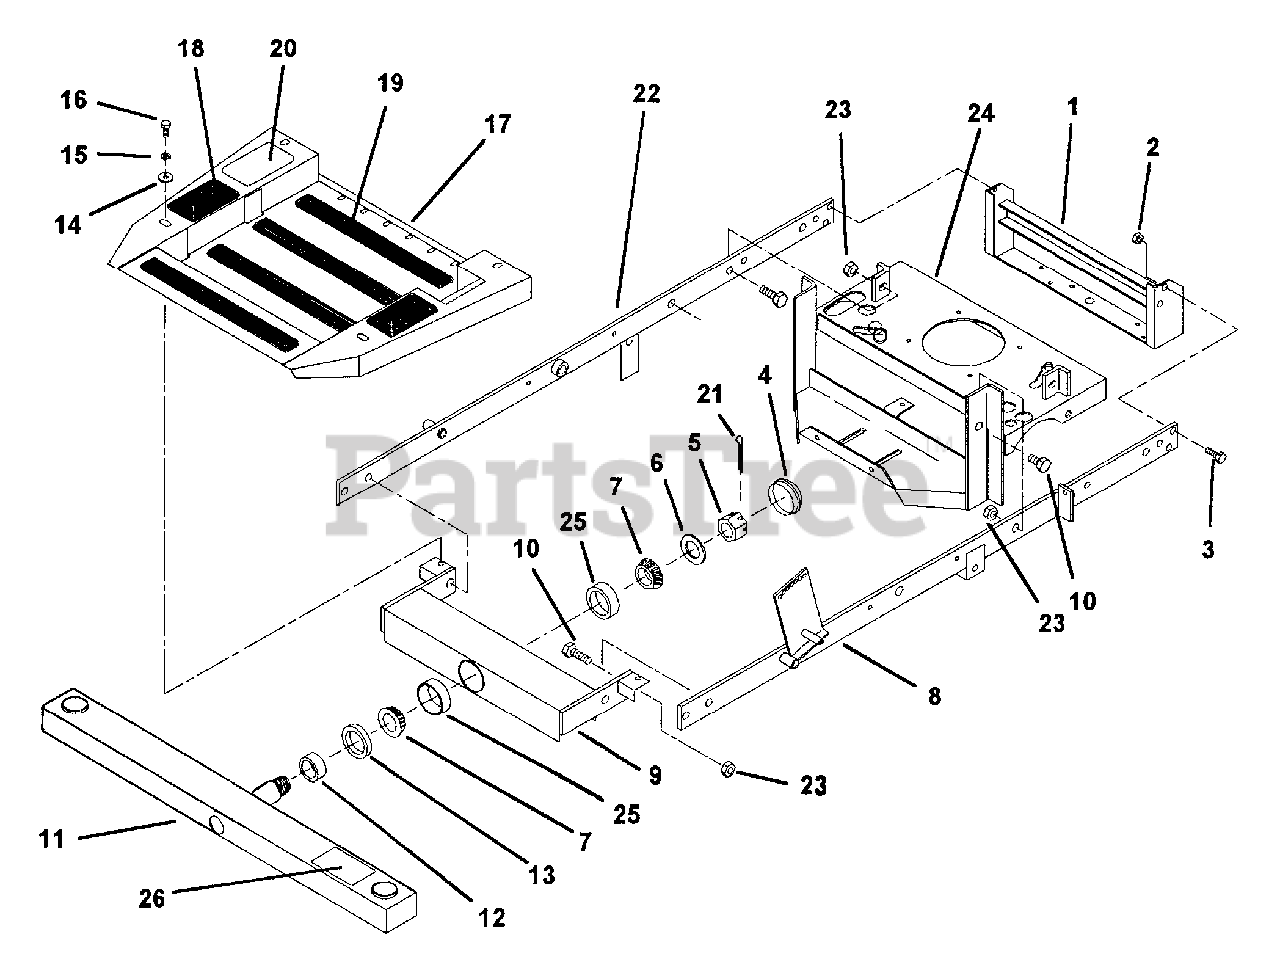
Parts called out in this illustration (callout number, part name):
1	REAR BUMPER WELDMENT
2	NUT, 3/8-16 NYLOC
3	BOLT, 3/8-16 X 1-1/4" GR.5
4	GREASE CAP
5	NUT, HEX. SLOTTED 1"-14
6	WASHER, 1" 10 GA.
7	BEARING CONE
8	FRAME SIDE L.H.
9	FRONT CHANNEL WELDMENT
10	BOLT, 1/2-13 X 1-1/4" GR.5
11	FRONT BUMPER/AXLE WELDMENT
12	BEARING SPACER
13	SEAL, OIL 1.688 SHAFT
14	WASHER, FLAT STD. 5/16"
15	LOCK WASHER, 5/16" HEAVY SPRING
16	BOLT, 5/16-18 X 3/4" GR. 5
17	FOOT DECK ASSEMBLY (w/ decal and tread pads)
18	TREAD PAD
19	TREAD PAD
20	DECAL, OPERATION INSTRUCTIONS
21	COTTER PIN, 3/16 X 2"
22	FRAME SIDE WELDMENT, R.H.
23	NUT, 1/2-13, STOVER
24	MOTOR MOUNT WELDMENT
25	BEARING CUP
26	DECAL, TOW WARNING
